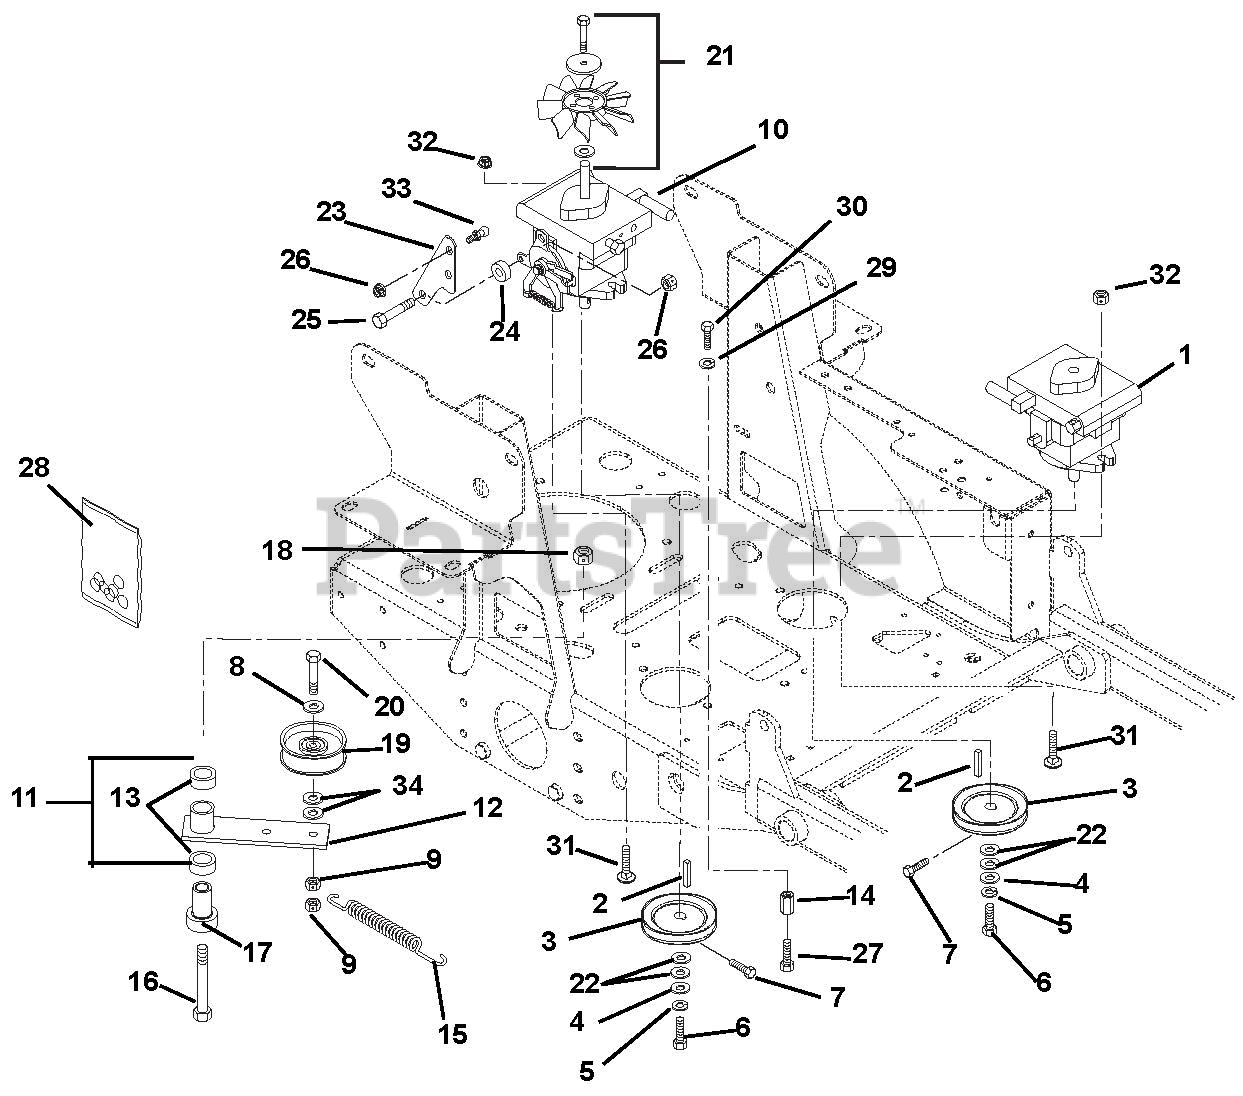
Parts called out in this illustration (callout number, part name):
1	Pump, Hydraulic BDP-10A Left Hand
2	Key, Straight 5mm x 25mm x 5mm
3	Sheave 4.0 x .199
4	Washer, Flat Steel .281 x 1.00 x .063
5	Washer, Locking .25 x .062
6	Bolt, Hex M6 x 1.00 x 12 Epoxy 30
7	Bolt, Hex .25-20 x .50 Grade 5
8	Washer, Flat Steel .406 x .812 x .065
9	Nut, Nyloc Flange .38-16
10	Pump, Hydraulic BDP-10A Right Hand
11	Assembly, Idler Arm Guard Drive
12	Weldment, Idler Arm Ground Drive
13	Bearing, 1.00 x 1.12 x .75
14	Nut, Coupling .375-16 x 1.75
15	Spring, Tension .120 x .845 x 6.50
16	Bolt, Hex .50-13 x 3.75 Grade 5
17	Bearing, Pedestal
18	Nut, Nyloc Flange .50-13
19	Idler, Flat 4.00 x .38 I.D.
20	Bolt, Hex .38-16 x 2.50 Grade 5
21	Fan, Cooling
22	Washer, Flat Steel .656 x 1.31 x .095
23	Bracket, Return to Neutral/Damper
24	Spacer .344 x 1.00 x .375
25	Bolt, Hex .31-18 x 1.25 Grade 5
26	Nut, Nyloc Flange .312-18
27	Bolt, Hex .38-16 x 1.50 Grade 5
28	Kit, Pump Seal (BDP-10A)
29	Washer, Locking .38 x .094
30	Bolt, Hex .38-16 x .75 Grade 5
31	Bolt-Round Head Square Neck .44-14 x 1.50 Grade 5
32	Nut, Nyloc Flange .44-14
33	Stud, Ball
34	Washer, Flat Steel .406 x 1.00 x .188
